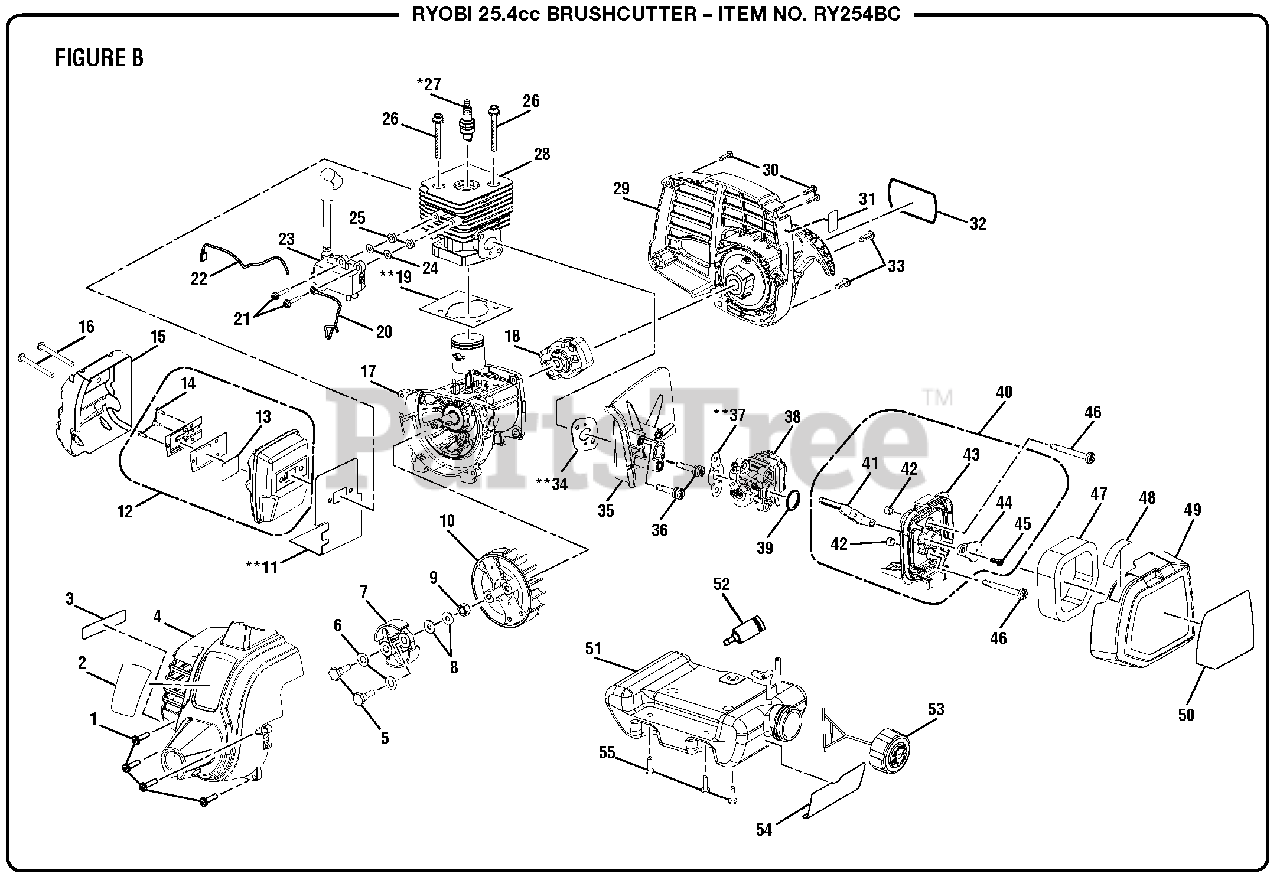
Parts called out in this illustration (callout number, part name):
1	Screw w/Washer (M5 x 20 mm, T20 Torx Pan Hd.)
2	Logo Label (Front)
3	Combustion Warning Label
4	Front Housing Assembly
5	Clutch Shoulder Bolt (M6 x 22.5 mm, Hex Hd.)
6	Curved Washer
7	Clutch Assembly
8	Washer (ID6 x OD15 x 1.2t)
9	Flywheel Nut
11	Muffler Gasket
12	Muffler Assembly
13	Screen
14	Screw (6-20 x 1/4 in., T20 Torx Pan Hd.)
15	Heat Shield
16	Screw (M5 x 50 mm, T25 Torx Pan Hd.)
17	Crankcase Assembly
18	Starter Cup
19	Gasket
20	Lead Wire (Red)
21	Screw w/Washer (M4 x 19 mm, T20 Torx Pan Hd. S.T.)
22	Lead Wire (Black)
23	Coil Boot Assembly
24	Washer (ID4.2 x OD10 x 1t)
25	Spacer (Phenolic)
26	Screw (M5 x 22 mm, Soc. Hd.)
27	Spark Plug (Champion RCJ4)
29	Rear Housing and Starter Assembly
30	Screw (M4 x 18 mm, T20 Torx Pan Hd. S.T.)
31	Primer Bulb Location Label
32	Logo Label (Rear)
33	Cap Screw w/Washer (M5 x 16 mm, T25 Torx Soc. Hd.)
34	Insulator Gasket
35	Heat Dam Insulator
36	Screw (M5 x 27 mm, T25 Torx Pan Hd. S.T.)
37	Gasket
38	Carburetor Assembly
39	Carburetor O-Ring
40	Airbox Base Assembly
41	Choke Lever
42	Compression Limiters
43	Air Box Base
44	Choke Plate
45	Screw (M4 x 12 mm, T20 Torx Pan Hd. S.T.)
46	Screw (M5 x 44 mm, T20 Torx Pan Hd.)
47	Air Filter
48	Choke Position Label
49	Airbox Cover
50	Starting Instructions Label
51	Fuel Tank and Cap Assembly
52	Fuel Filter
53	Fuel Cap Assembly
54	Fuel Mixture Label
55	Shoulder Screw (M4 x 14 mm, T25 Torx Truss Hd. S.T.)
